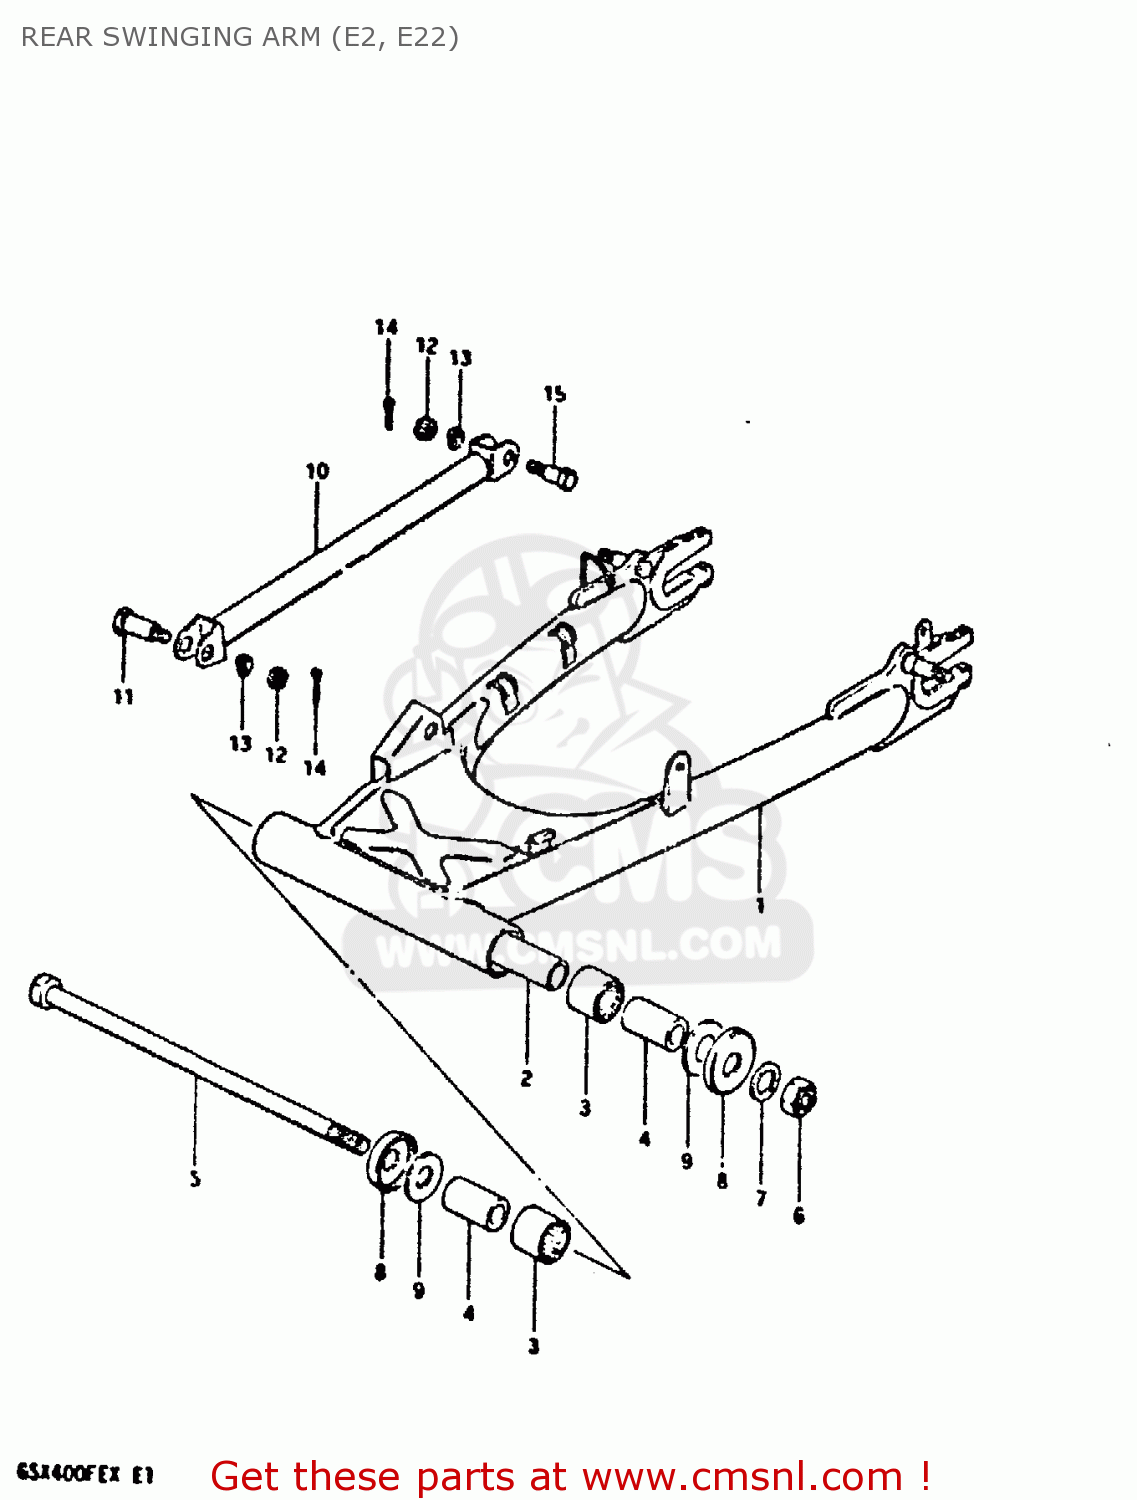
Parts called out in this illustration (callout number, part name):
1	REAR SWINGING ARM
2	SPACER
3	BEARING(22X29X30)
4	SPACER,RR SWGARM PIVOT
5	SHAFT,REAR SWING ARM
6	NUT 14MM
7	WASHER
8	CVR,RR SWGARM DUST SEAL(OD:40)
9	WASHER(14.2X34X1)
10	TORQUE LINK, REAR
11	BOLT(10X24.5)
12	NUT
13	WASHER
14	PIN 20X20
15	BOLT(10X39)
